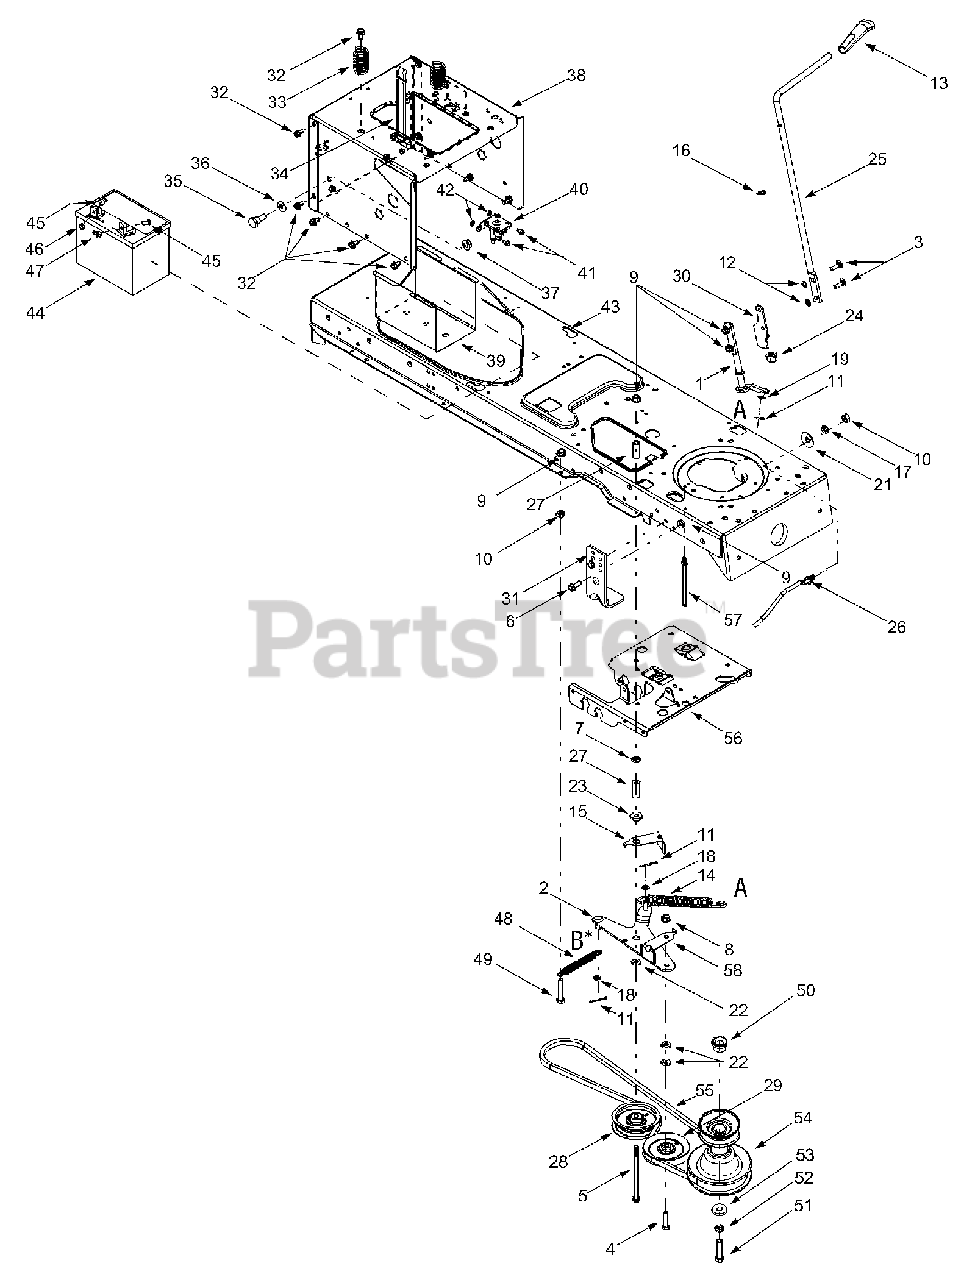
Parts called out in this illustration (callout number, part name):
1	PTO Engage Lever Assembly
4	Hex Cap Screw, 3/8-16 x 1.5
5	Hex Cap Screw, 3/8-16 x 5.5
6	Hex Head Washer Screw, 5/16-18 x .875
7	Push Nut, 3/8
8	Flange Lock Nut, 3/8-16
9	Flange Lock Nut, 5/16-18
10	Hex Nut, 5/16-18
11	Cotter Pin, 1/8 x 1.25
12	Speed Nut, .3125
13	PTO Knob
14	Extension Spring, .75 x 6.75
15	Belt Guard
16	Flat Washer, .510 x .750 x .033
17	Lock Washer, 5/16
18	Flat Washer, .385 x .62 x .063
19	Flat Washer, 5/16
21	Bell Washer, .39 x 1.13 x .062
22	Flat Washer, .407 x .812 x .135
23	Shoulder Spacer, .380
24	Hex Split Flange Bearing, .5
26	Belt Keeper Rod
27	Spacer, 3/8 x 1.54
28	Idler Pulley, 3.5
29	Idler Pulley, 4.0
32	Self Tapping Screw, 5/16-18 x .625
33	Compression Spring, 1.28 x 3.5
34	Battery Strap
35	Shoulder Screw, .625 x .5, 7/16-20
36	Bell Washer, .45 x 1.0 x .062
37	Flange Lock Nut, 7/16-20
41	Self Tapping Screw, 1/4-20 x .5
42	Lock Washer, 1/4
45	Hex Cap Screw, 1/4-20 x .62
46	Hex Sems Nut, 1/4-20
47	Wing Nut, 1/4-20
48	Extension Spring, .50 x 5.0
49	Hex Cap Screw, 5/16-18 x 1.75
50	Spacer Cup
51	Hex Head Cap Screw, 7/16-20 x 1.25
52	Lock Washer, 7/16
53	Flat Washer, .450 x 1.25
54	Engine Pulley, 3.56 OD x 5.56
55	PTO Belt
57	Keeper Pin, 5/16 x 4.75
58	Belt Guard
